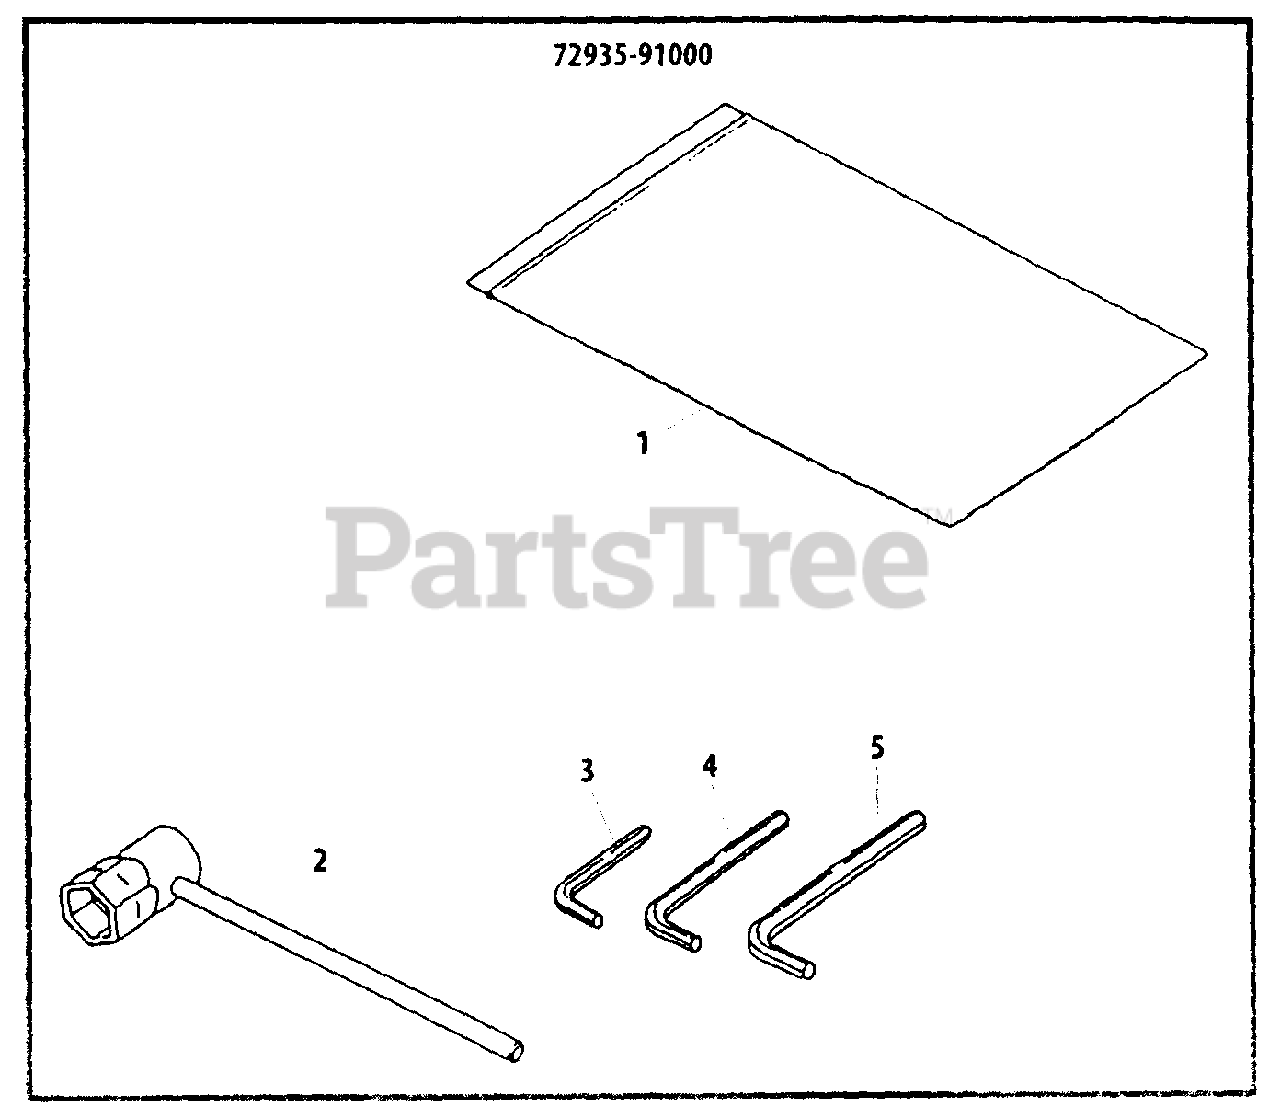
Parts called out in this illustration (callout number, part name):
1	BAG, TOOL
2	SOCKET WRENCH
3	HEX KEY - 3mm
4	HEX KEY - 4mm
5	HEX KEY - 6mm
72935-91000	TOOL KIT
